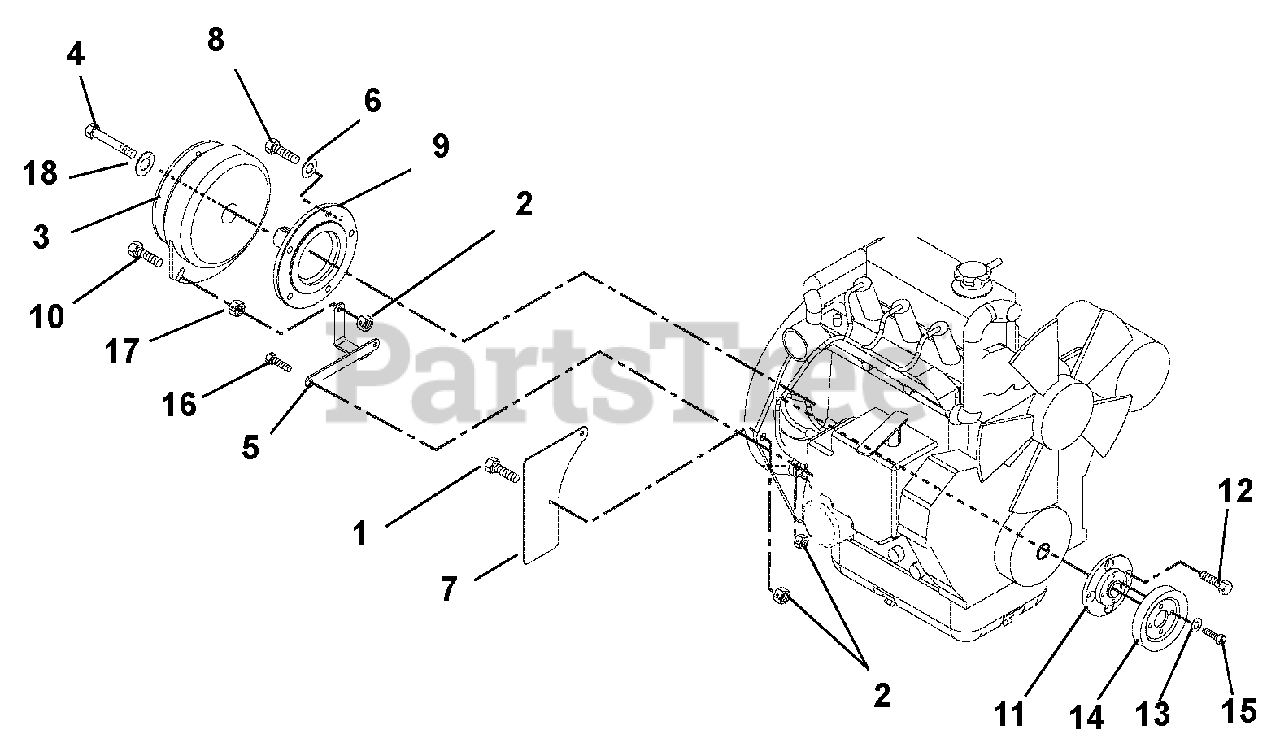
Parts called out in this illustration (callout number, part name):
1	Bolt, Hex .31 -18 x .75 Grade 5
2	Nut, Locking Top Flange .31-18
3	Clutch, Warner
4	Bolt, Hex .44-20 x 2.50 Grade 5 YZ EP80
5	Stabilizer, Clutch
6	Washer, Lock .31 x .078 Regular
7	Guard, Flywheel
8	Bolt, Hex M8 x 1.25 x 25 Grade 8
9	Stub Shaft
10	Bolt, Hex .31-18 x 1.50 Grade 5
11	Adapter, Sheave
12	Bolt, M8-1.25 x 25
13	Washer, Locking .25 x .062
14	Sheave, Poly-V 1.0 x 3.25
15	Bolt, Hex .25-20 x .75 Grade 5
16	Bolt, Hex .31-18 x 1.00 Grad 5
17	Nut, Hex .31-18
18	Washer, Locking .44 x .109 Regular
NS	Kit, Break Pole Module Replacement
